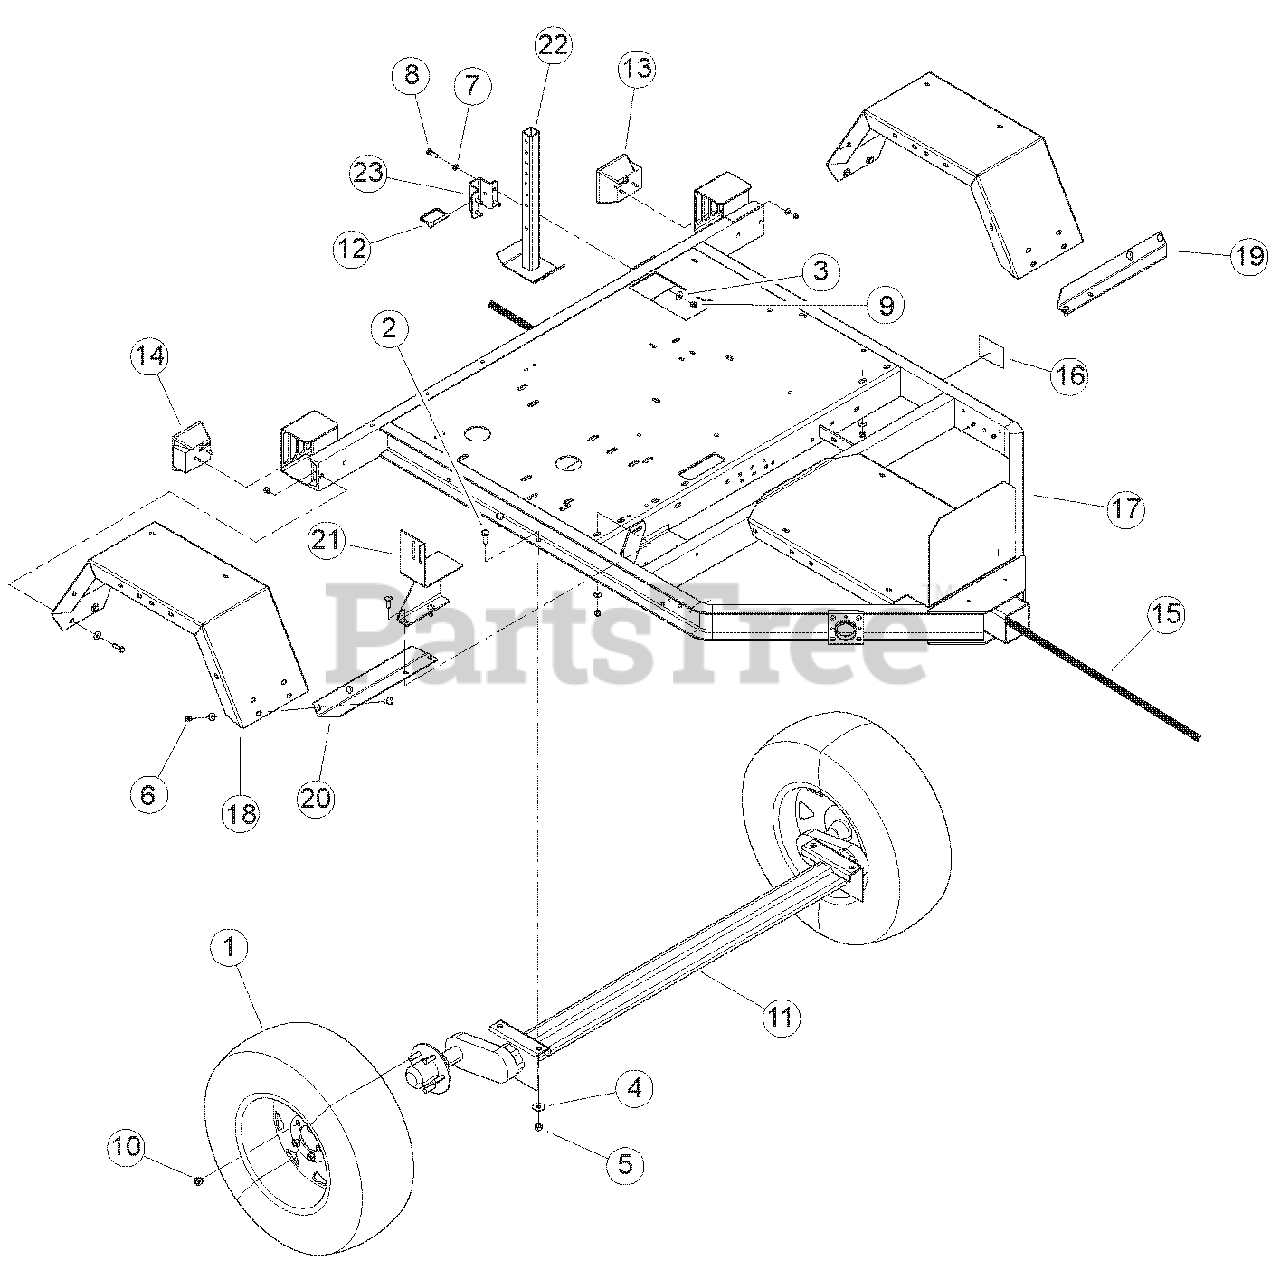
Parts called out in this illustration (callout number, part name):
1	ASSEMBLY, 15 IN. TIRE & WHEEL
2	BOLT, 1/2 X 1-1/4 HEX HD GR5 NC ZP
3	WASHER, 3/8 FLAT ZP
4	WASHER, 1/2 FLAT ZP
5	NUT, 1/2 CENTERLOCK GRB ZP
6	BOLT, 3/8 X 1 CRG GR5 NC ZP
7	WASHER, 3/8 SAE FLAT ZP
8	BOLT, 3/8 X 1-1/4 HEX HD GR5 ZP
9	NUT, 3/8 NE NYLOCK ZP
10	NUT, 1/2 -20 WHEEL
11	AXLE, 3000 LB. TORSION
12	PIN, 3/8 X 2-3/4 SNAP
13	LIGHT, LH TAIL
14	LIGHT, RH TAIL
15	HARNESS, TRAILER LIGHT
16	DECAL, P215/70R15 LOAD RATING
17	WELDMENT, CHIPPER TRAILER
18	FENDER, HEAVY DUTY
19	ANGLE, FENDER MOUNT LH
20	ANGLE, FENDER MOUNT RH
21	WELDMENT, BELT GUIDE
22	WELDMENT, REAR STABILIZER
23	GUIDE, TRAILER SUPPORT
